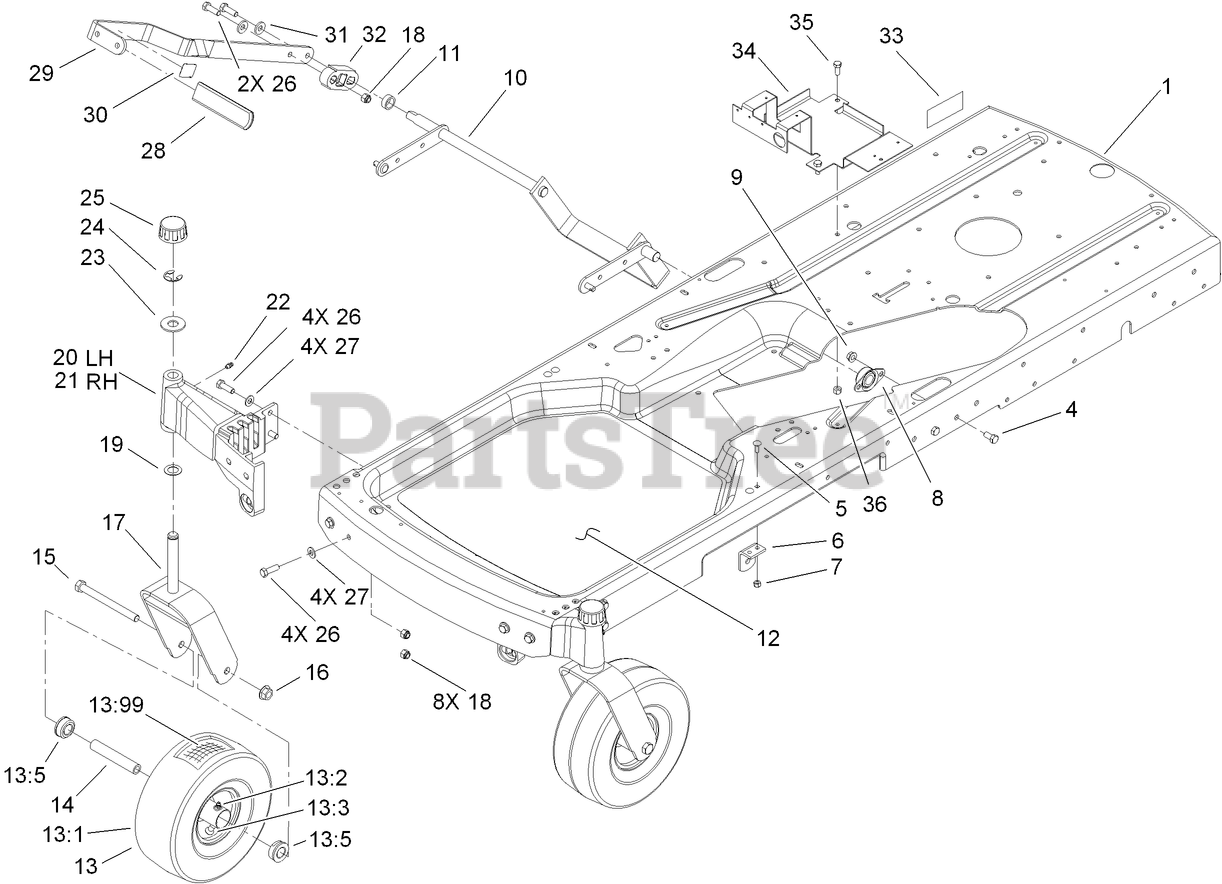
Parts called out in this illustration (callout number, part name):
4	SCREW-HH
5	BOLT-CARR
6	BRACKET-LIFT
7	NUT-LOCK, NI
8	BEARING-FLANGE, SIDE
9	NUT-HHF, WHIZ
10	LIFT ARM ASM
11	SPACER
12	PAD-ANTISKID
13	FRONT WHEEL AND TIRE ASM
13:2	FITTING-GREASE
13:5	BUSHING-FLANGE
13:99	TUBE-INNER (W/VALVE)
14	BUSHING-SPANNER
15	SCREW-HH
16	NUT-HF
17	CASTER FORK ASM
18	NUT-LOCK, NI
19	WASHER-THRUST
21	CASTER-RH
22	FITTING-GREASE
23	WASHER-PLAIN
24	RING-RETAINING, EXT
25	CAP-HUB
26	SCREW-HH
27	WASHER-FLAT
28	GRIP-LEVER, LIFT
29	LEVER-LIFT
30	DECAL-HOC
31	WASHER-BELLEVILLE
32	BLOCK-LIFT
33	DECAL-TRANSPORT
34	HOLDER-BATTERY
35	SCREW-HH
36	NUT-LOCK, NI
